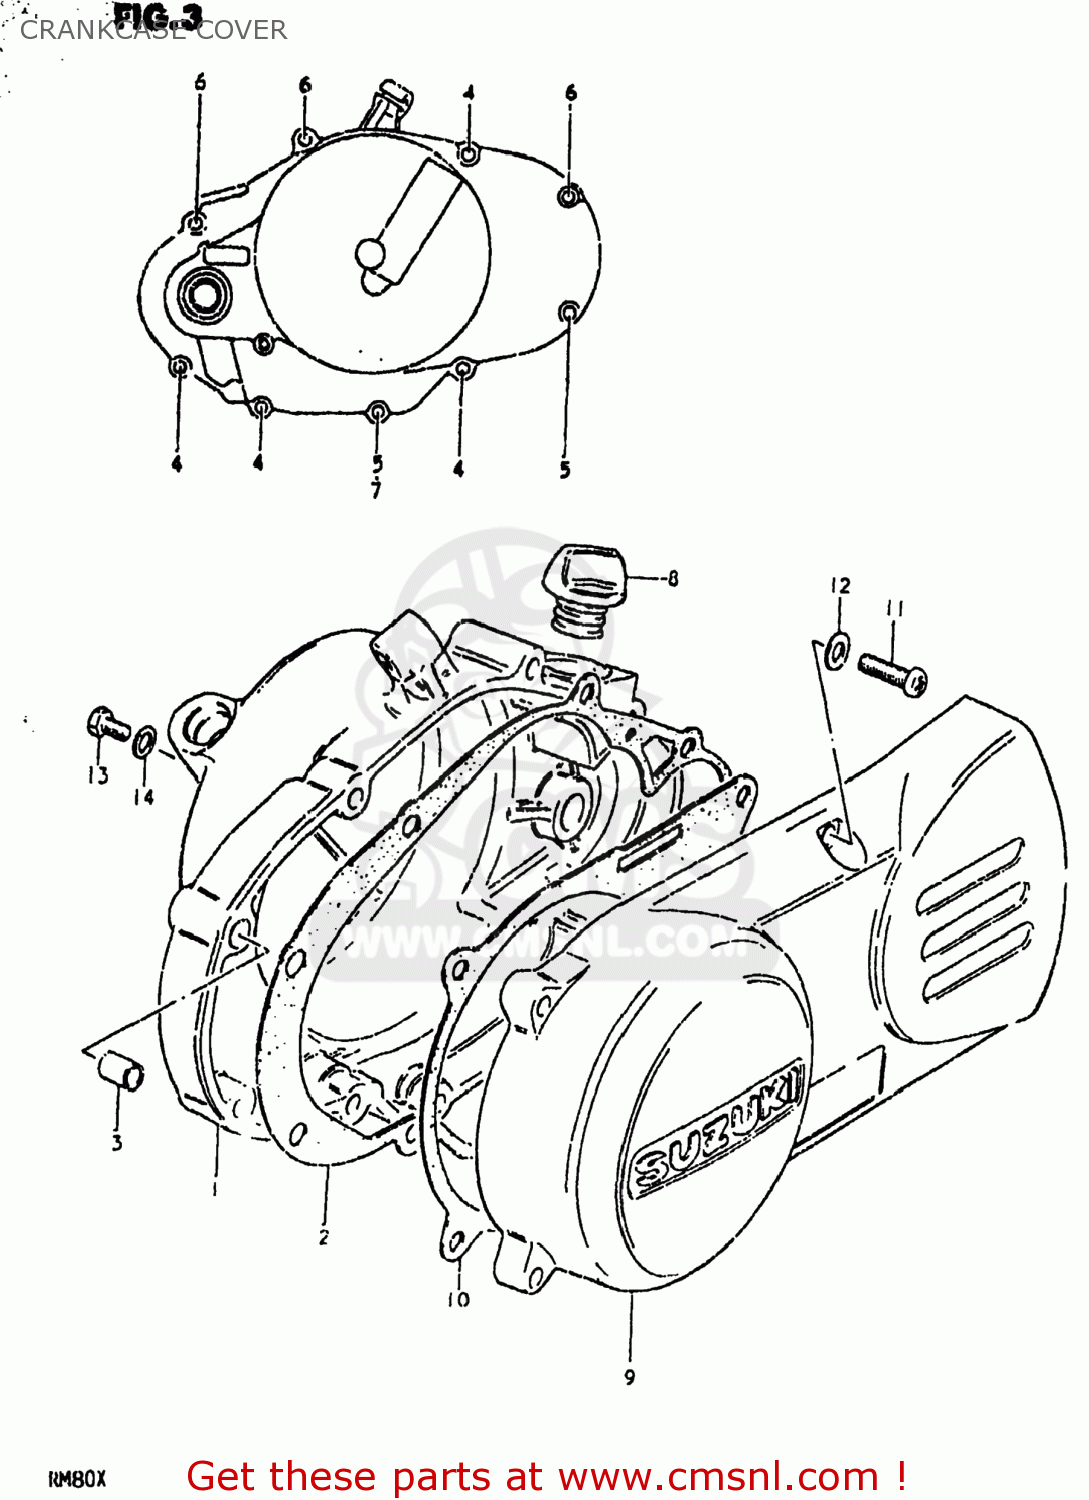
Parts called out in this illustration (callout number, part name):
1	COVER,CLUTCH
2	GASKET,CLUTCH COVER (MCA)
3	PIN
4	SCREW
5	SCREW 6X30
6	SCREW
7	GASKET(6.2X11X1).2 (NAS)
8	PLUG
9	COVER,MAGNETO
10	GASKET,MAGNETO COVER (NAS)
11	SCREW
12	WASHER
13	SCREW(6X10)
14	GASKET(6.2X11X1) (NAS)
